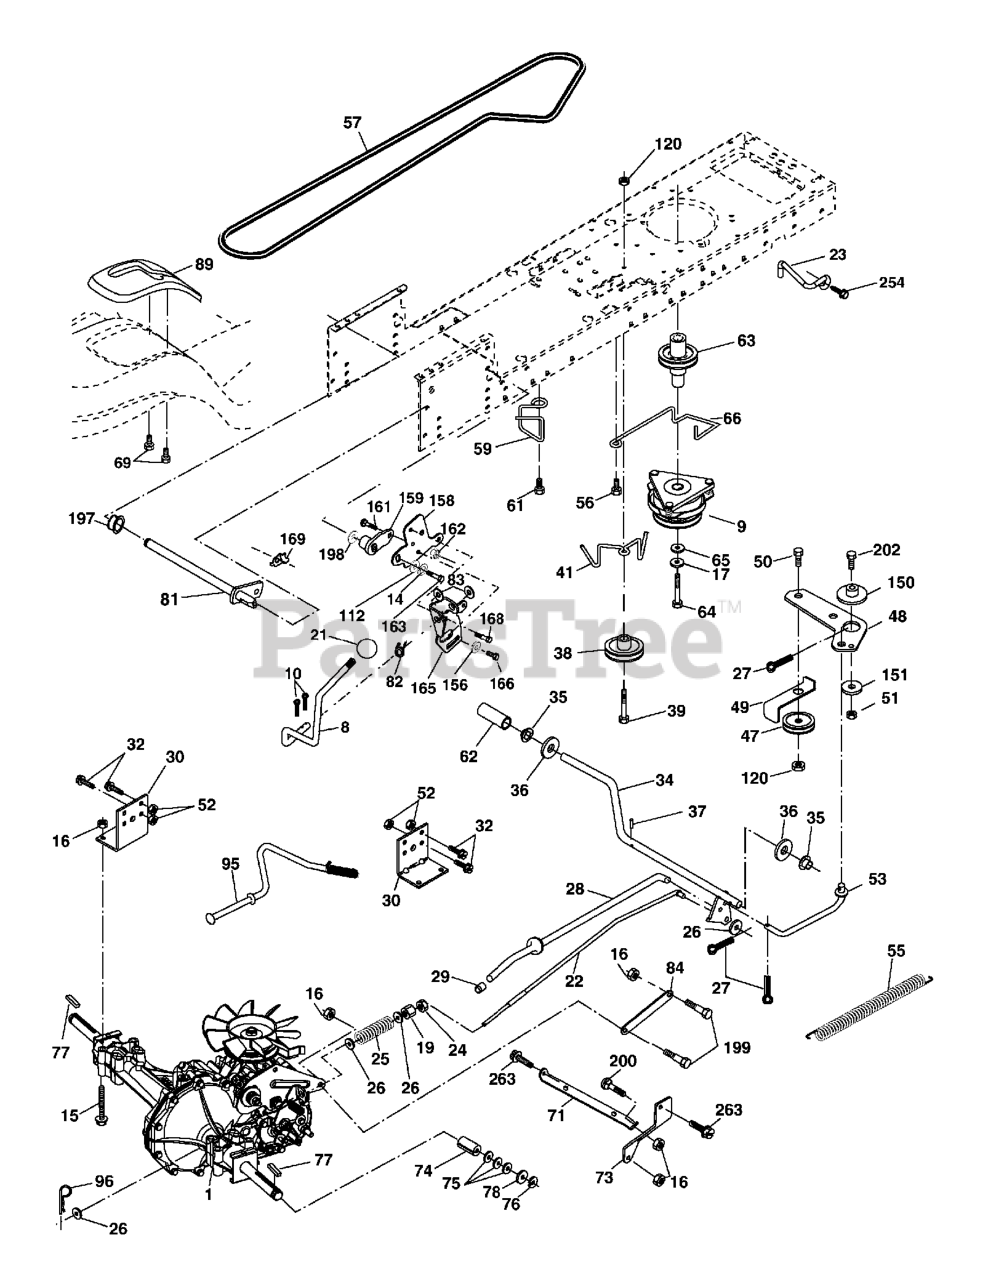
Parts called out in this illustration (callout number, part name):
8	ROD.SHIFT.FENDER.ADJ.STLT
9	CLUTCH ELECTRIC
10	PIN COTTER
14	LOCKWASHER
15	BOLT HEX 5/16-18 GR 5
16	NUT.71038.31-18.HEX.NYLOCK
17	WASHER
19	NUT
21	KNOB.DELUXE.(PISTOL.GRIP).BLAC
22	ROD BRAKE HYDRO
23	BRACKET, ANTI-ROTATION
24	NUT
25	SPRING ROD LT
26	WASHER
27	COTTER PIN
28	ROD, PARKING BRAKE
29	PLUNGER CAP
30	BRKT, TRNSXLE MNT 20"
32	BOLT
34	SHAFT, FOOT PEDAL
35	BEARING.NYLON
36	WASHER LT
37	DRIVE PIN
38	PULLEY IDLER COMPOSITE
39	BOLT
41	KEEPER, BELT IDLER
47	IDLER PULLEY
48	BELLCRANK, CLUTCH
49	RETAIN BELT
50	BOLT.3/8-16X1.50
51	LOCKNUT
52	LOCKNUT
53	LINK, CLUTCH LT
55	SPRING, RETURN LT
56	SCREW.3/8-16
57	DRIVE BELT, LTH & YTH TRACTORS
59	KEEPER, BELT CENTER
61	SCREW 3/8-16X.875
62	PEDAL COVER T
63	PULLEY- ENGINE
64	BOLT HEX 7/16-20X4-1/4"
65	LOCKWASHER
66	KEEPER BELT ENGINE
69	SCREW.HI-LO.CONSOLE
71	STRAP TORQUE LH HYDRO
73	STRAP TORQUE RH HYDRO
74	SPACER AXLE
75	WASHER
76	E-RING LT
77	SQUARE KEY
78	WASHER
81	SHAFT ASM CROSS TAPERED
82	SHIFT SPRING
83	WASHER
84	LINK TRANSAXLE
89	CONSOLE, SHIFT, STL, AUTO GREY
95	CONTROL ASM. BYPASS HYDRO
96	RETAINER M
112	WASHER LT
120	NUT LOCK FLG 3/8-16 UNC
150	SPACER, RETAINER
151	WASHER 12/32X2X10GA
156	WASHER.SRRTD.5/16
158	BRACKET
159	RB HUB.SHIFT
161	BOLT
162	NUT.CROWNLOCK.1/4
163	BOLT
165	RP BRACKET
166	CAPSCREW.HXHD.FLG.5/16-18X.625
168	BOLT.SHOULDER.5/16-18X
169	PLATE.FASTENING.CROSS.SHAFT
197	NYLINER SNAP 5/8" ID
198	WASHER.NYL.7/8IDX.105"HYD CR
199	BOLT SHOULDER 5/16-18 UNC
200	BOLT
202	BOLT
254	SCREW 3/8-16X1
263	SCREW, 3/8-16X3/4
